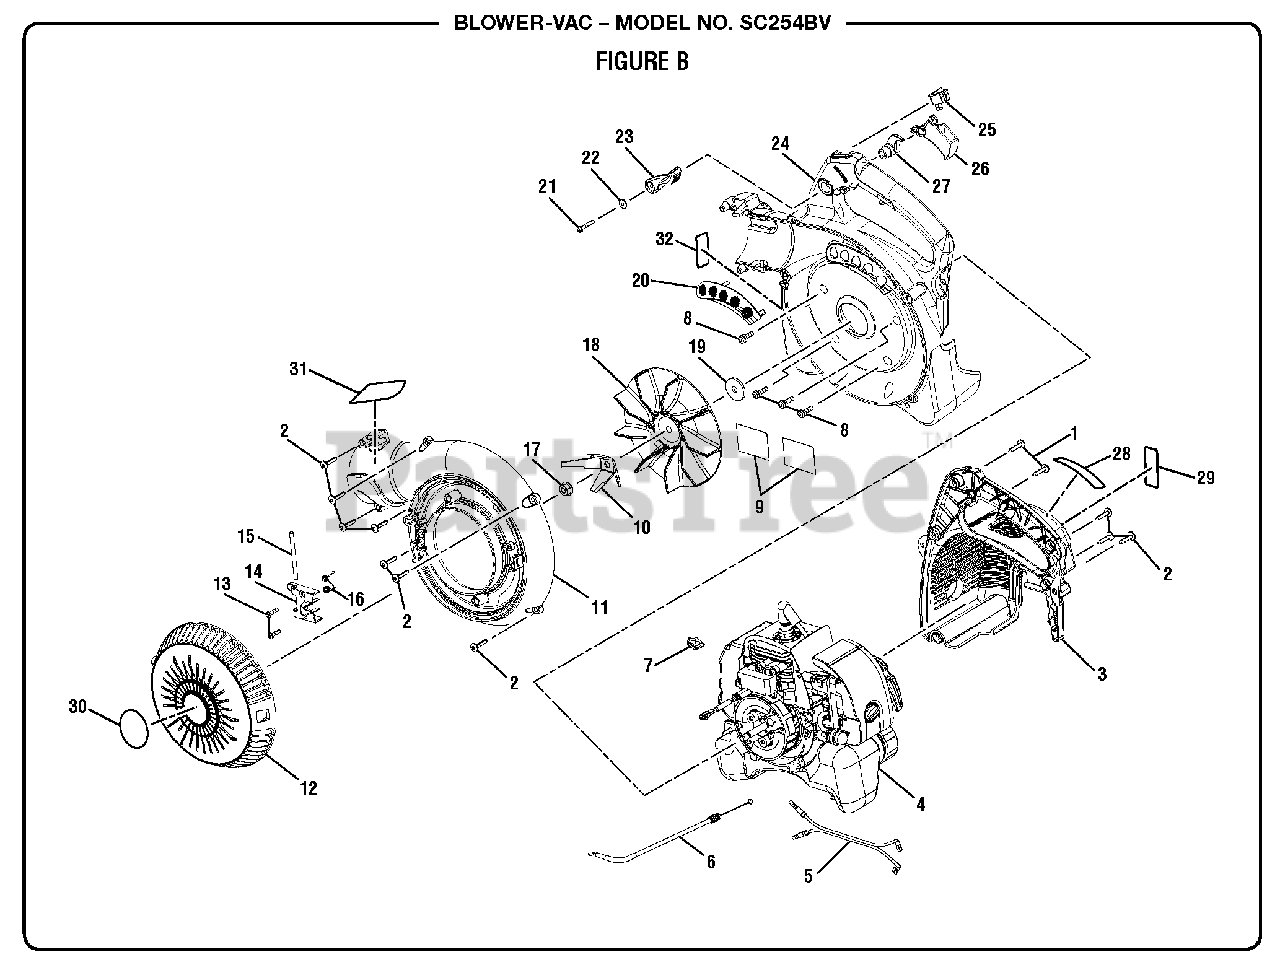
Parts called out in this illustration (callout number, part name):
1	Screw (10-14 x 7/8 in., T25 Torx T.F.)
2	Screw (10-14 x 7/8 in., T25 Torx Pan Hd. T.F.)
3	Engine Shroud
5	Wiring Harness
6	Throttle Cable
7	Rubber Grommet
8	Screw w/Washers (M5 x 20 mm, T25 Torx Pan Hd.)
9	Heat Shield Tape
10	Mulcher Blade
11	Outer Housing
12	Vacuum Door
13	Screw (8-14 x 5/8 in., Pan Hd.)
14	Vacuum Door Hinge
16	Hinge Spring
17	Lock Nut (M8 x 1.25, Flange Hd.)
19	Washer (ID9.8 x OD30 x 3t)
20	Mesh Screen
21	Screw (8-14 x 1 in., Special T20 Torx Truss Hd. T.F.)
22	Washer (ID4.3 x OD12 x 1.5t)
23	Cruise Control Lever
24	Inner Housing
25	Engine Switch
26	Throttle Trigger
27	Throttle Lock (Cruise Control)
28	Warning Icon Label
29	Choke Label
30	Vacuum Door Label
31	Tube Removal Label
32	Combustion Warning Label
